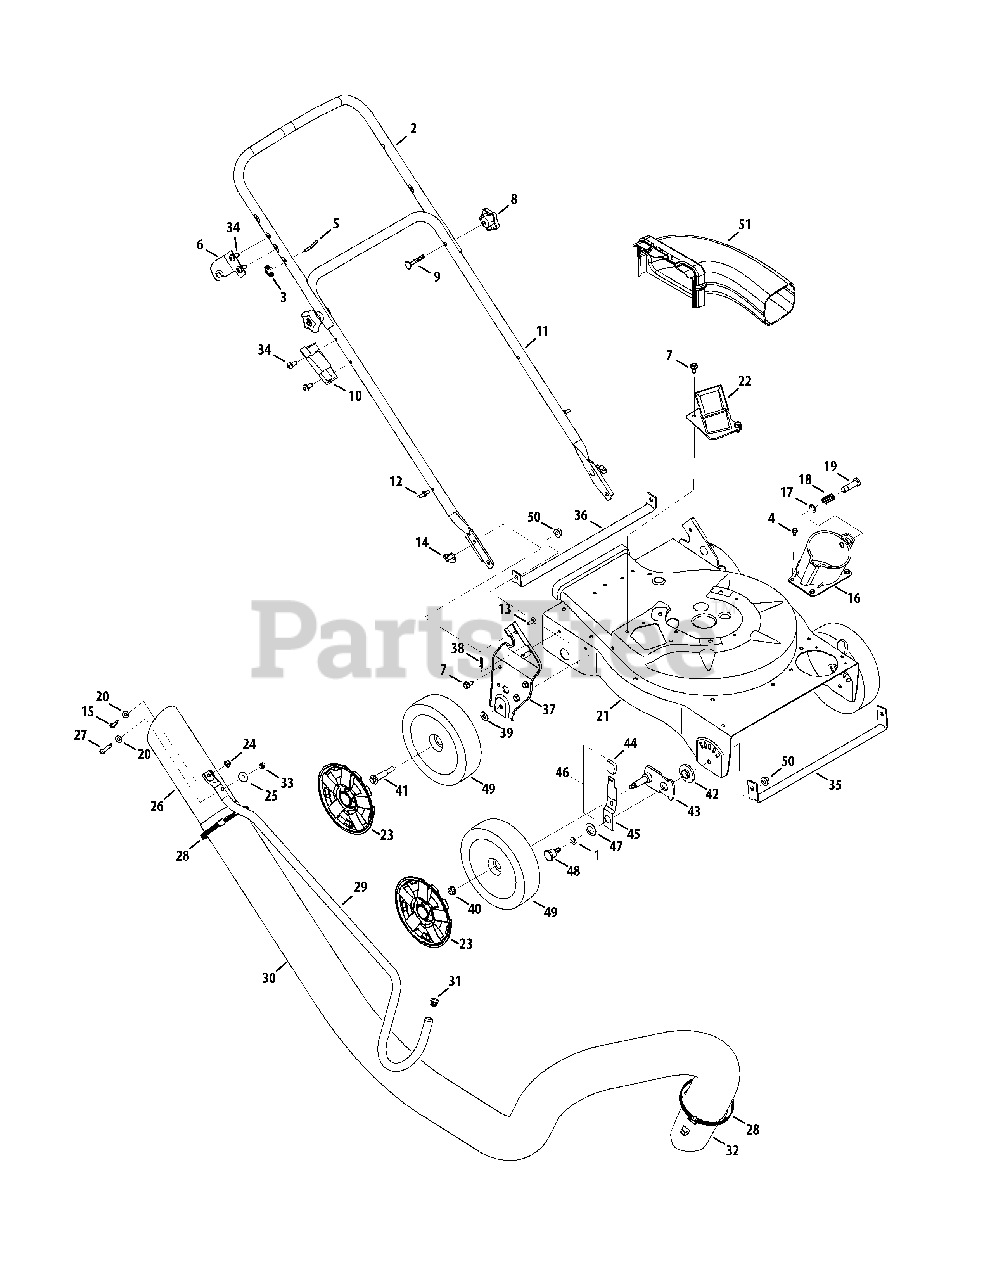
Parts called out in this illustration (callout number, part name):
1	Thrust Washer.375 ID x.70 OD
2	Upper Handle
4	Screw, 1/4-20 x .500
5	Eye Bolt
6	Upper Handle Bracket
7	Hex Cap Screw 5/16-12 x.750
8	Star Knob
9	Carriage Bolt
10	Nozzle Handle Clip
11	Lower Handle
13	Carriage Screw 1/4-20 x.75
14	Wing Nut 1/4-20
15	Hex Cap Screw 1/4-20 x .62
16	Hose Base Adapter Assembly
17	E Ring.500 Dia
18	Compression Spring
19	Clevis Pin
20	Flat Washer.271 ID x.630 OD
21	Upper Flail Housing
22	Chipper Chute Assembly
23	Hubcap, 8"
24	Flange Lock Nut 1/4-20
25	Spacer
26	Hose Nozzle
27	Hex Cap Screw 1/4-20 x 1.62
28	Adjustment Clamp
30	Vacuum Hose
31	Handle Plug
32	Hose Adapter, Briggs
33	Cap Lock Nut, 1/4-20
34	TT Screw, 5/16-18 x .750
35	Front Wheel Support Brace
36	Rear Wheel Support Brace
37	Handle Bracket Ass’y RH
37	Handle Brkt Ass’y LH
38	Cotter Pin
39	Bell Washer.401 ID x.870 OD
40	Flange Lock Nut, 3/8-16
41	Shoulder Screw 3/8-16
42	Height Adjustment Bearing
43	Pivot Arm Assembly
44	Height Adjustment Knob
45	Spring Lever
46	Height Lever Assembly
47	Bell Washer.760 ID x.25 OD
48	Shoulder Screw,.750 x.500
49	Wheel, 8 x 2
50	Flange Lock Nut, 3/8-16
51	Blower Chute Assembly
